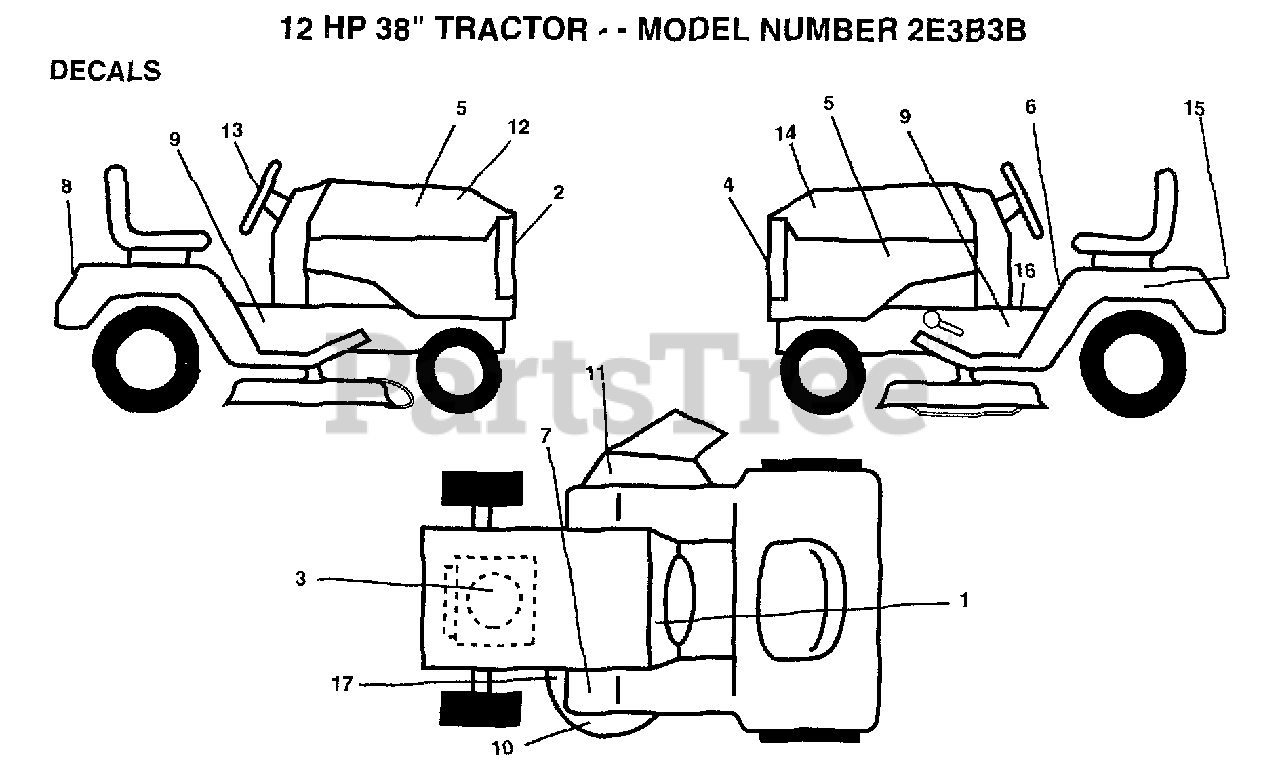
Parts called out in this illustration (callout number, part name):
1	DECAL.DASH.INSTR.
2	GRILL DECAL
3	DECAL.ENG.271967
5	"DECAL,HOOD"
6	DECAL CAUTION
7	DECAL T
8	FENDER DECAL
11	"DECAL, WARNING"
12	DECAL HOOD RH RLY
13	"DECAL,STR WHL"
14	DECAL HOOD LH RLY
15	DECAL
16	DECAL BRAK PARK
17	DECAL
